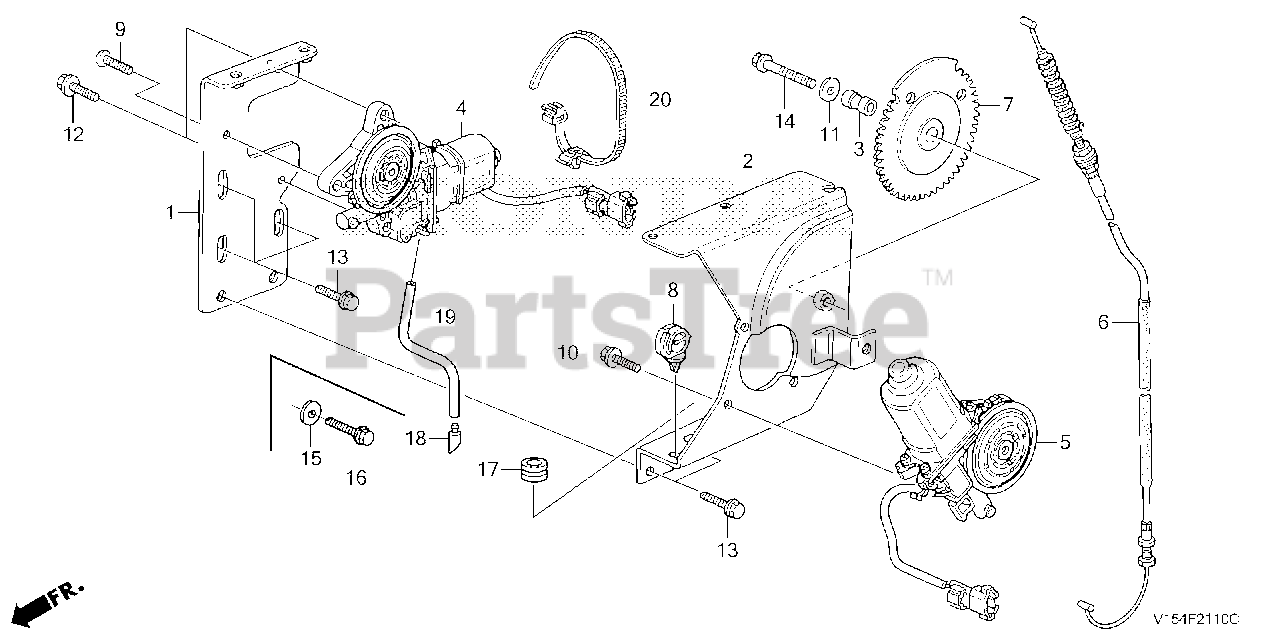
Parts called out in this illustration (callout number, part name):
1	BRACKET, CHUTE MOTOR
2	BRACKET, CHUTE GUIDE MOTOR
3	COLLAR, CLUTCH GUIDE GEAR
4	MOTOR ASSY., CHUTE
5	MOTOR ASSY., CHUTE GUIDE
6	CABLE, CHUTE GUIDE
7	GEAR, CHUTE GUIDE MOTOR
8	CLIP, WIRE HARNESS (25MM)
9	SCREW, PAN (6X12)
10	SCREW, TAPPING (5X14)
11	WASHER, PLAIN (6MM)
12	BOLT, FLANGE (6X12) Use up to Engine SN 1543277.
13	BOLT, FLANGE (6X12) Use up to Engine SN 1543277.
14	BOLT, FLANGE (6X30)
15	WASHER, PLAIN (6MM)
16	BOLT, FLANGE (6X16) Use from Engine SN 2056820.
17	RUBBER, TURN SIGNAL BOLT MOUNTING (NOT AVAILABLE)
18	BELL, MOUTH
19	BULK HOSE, VACUUM (3.5X1000) (3.5X75)
20	BAND, WIRE HARNESS
